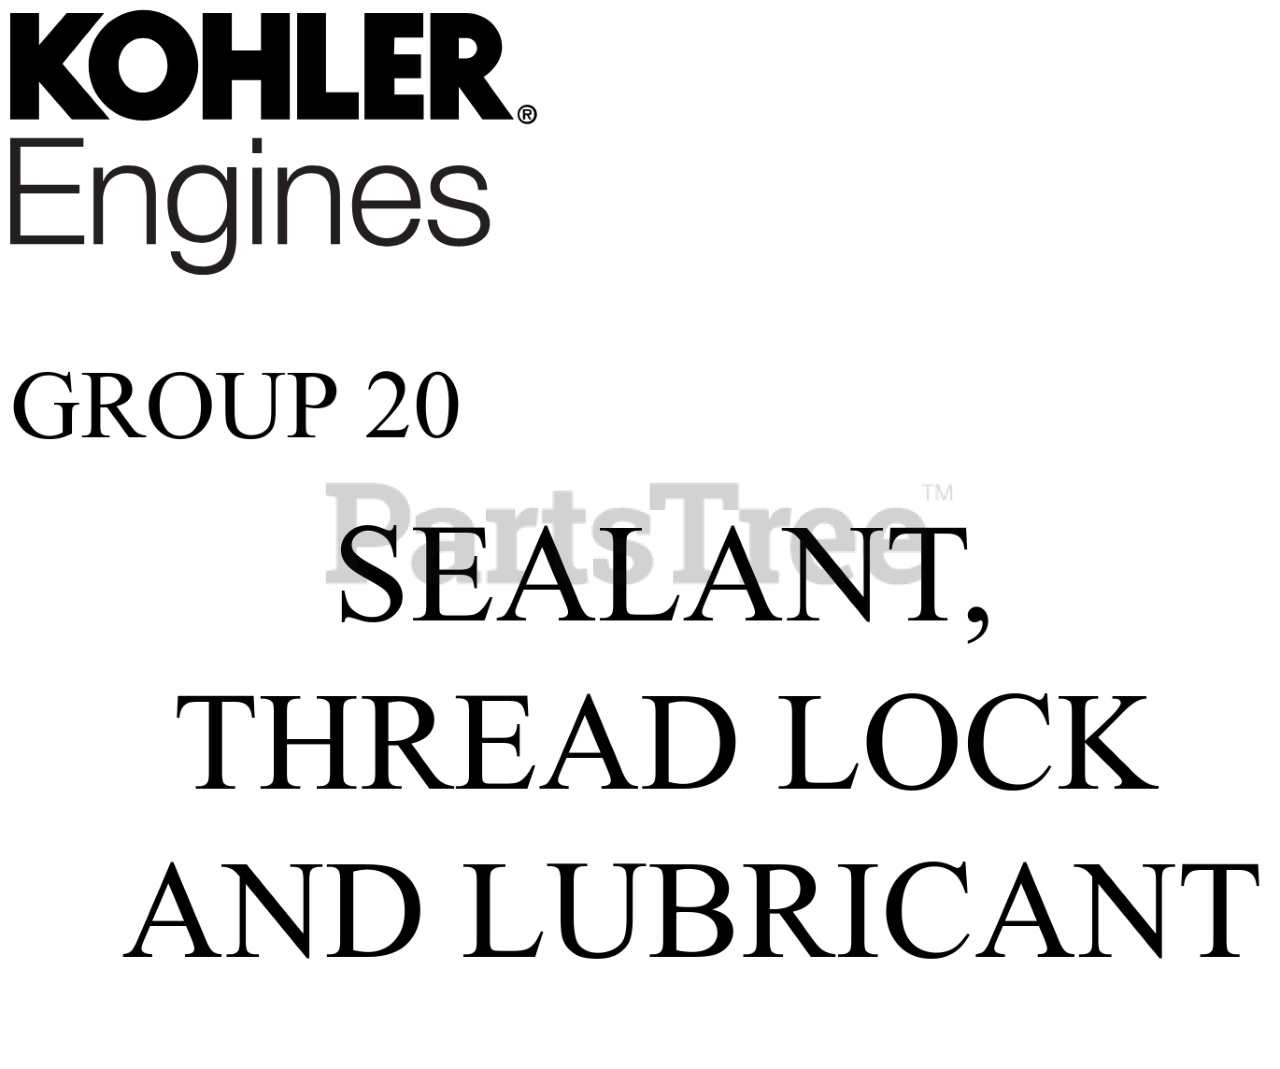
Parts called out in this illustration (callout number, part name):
NI	QUART OF OIL - SAE30
NI	QUART OF OIL - 10W30-USE 25 357 65-S
NI	LUBRICANT, GREASE (SPLINE)
NI	LUBRICANT, CAMSHAFT
NI	20W50 OIL (QUART)-USE 25 357 68-S
NI	SEALANT(LOCTITE 620)-(#2559711S)
NI	SEALANT(LOCTITE 222 RETAIN CMPND 0.5ML)
NI	SEALANT(LOCTITE INSTANT GASKET 4 OZ)
NI	LUBRICANT, BENDIX STARTR
